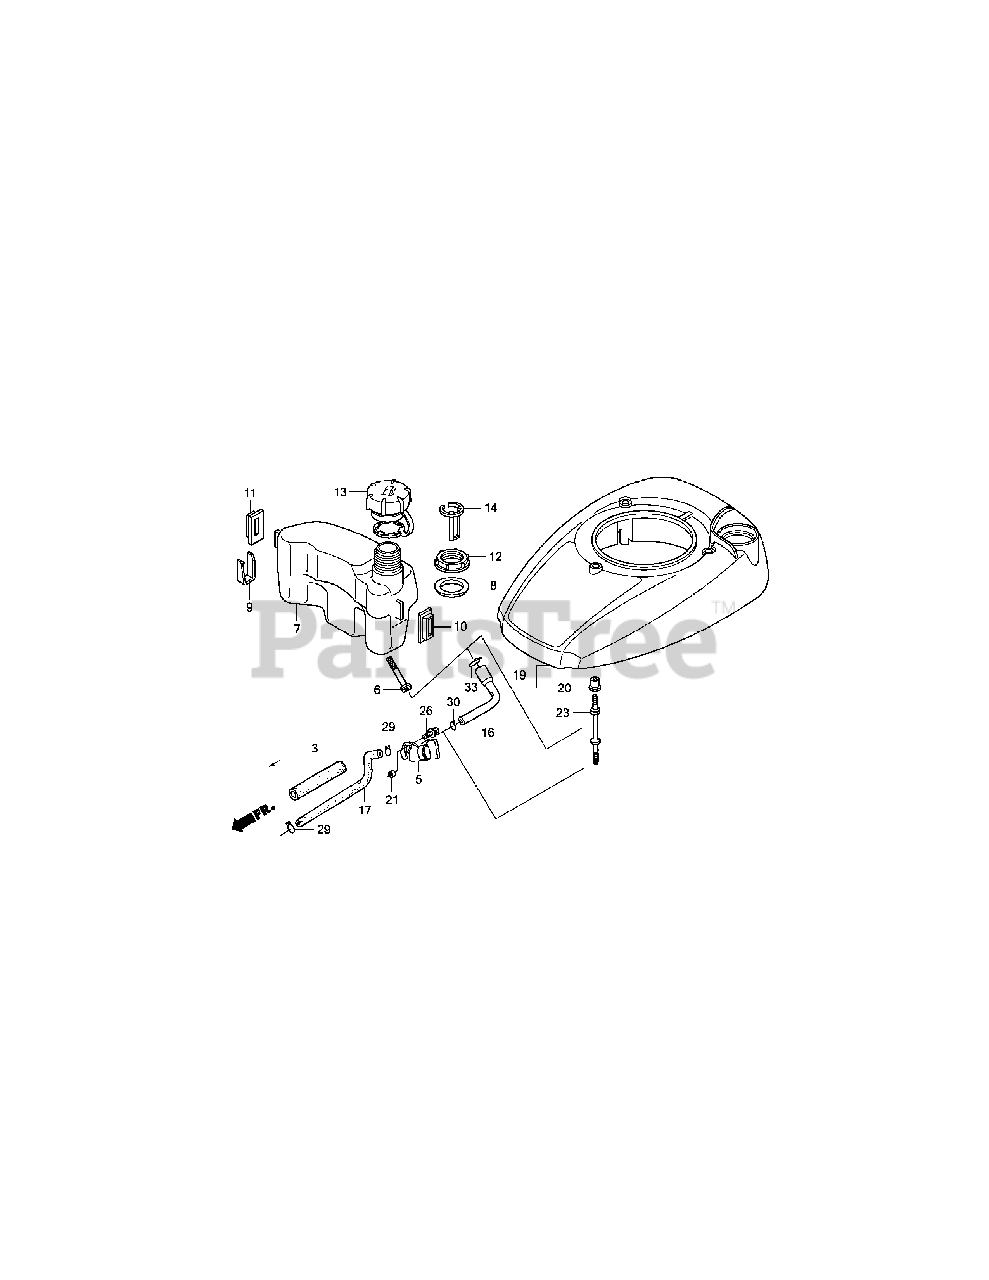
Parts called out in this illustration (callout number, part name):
3	Fuel Line Sleeve
5	Petcock Assembly
6	Fuel Filter
8	Fuel Filler Neck Seal
9	Tank Mounting Clip
10	Tank Mounting Rubber
11	Tank Mounting Rubber
12	Tank Mounting Nut
13	Fuel Cap Assembly
14	Fuel Level Gauge
16	Fuel Tank Tube
19	Fan Cover, Black
20	Fan Cover Collar
21	Fuel Petcock Collar
23	Stud Bolt, 42.5mm
26	Screw w/ Washer, 5 x 10
29	Tube Clip, B8
30	Tube Clip, B10
33	Tube Clip, C11
